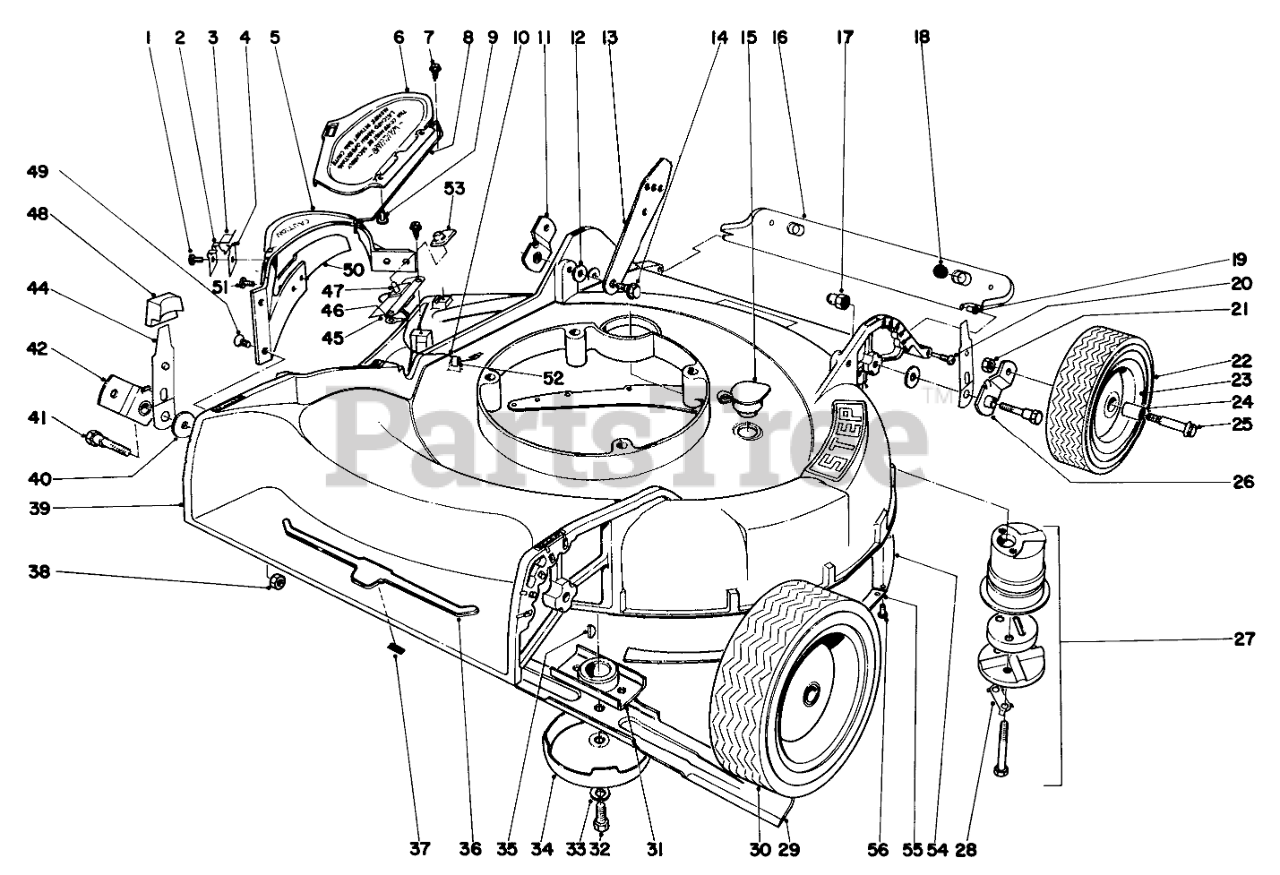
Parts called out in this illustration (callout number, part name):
2	Lower Clip
3	Upper Clip
4	Wear Plate
5	Deflector
6	Deflector (Incl. Ref. #8 & #9)
7	SCREW-HWHTF
8	Hinge Pin
9	Rivet
10	Lead Wire
11	Pivot Arm
12	SPACER
13	Handle Latch
14	SCREW-SHOULDER
15	WASHOUT PLUG
16	Safety Shield (Incl. Ref. #18 & #19)
17	Nut
18	SKID BUTTON
19	SAFTEY SHIELD BUSHING
20	SAFTEY SHIELD SCREW
21	Nut
22	8 TIRE
23	Wheel (Incl. Ref. #24)
24	Bushing
26	Pivot Arm
27	Muffler
28	CLIP - LOCKING
29	Blade
31	BLADE RETAINER WA
32	SPECIAL SCREW
33	WASHER-LOCK
34	AntiScalp Cup
35	KEY-WOODRUFF
36	Emblem, Bullshead
38	Nut
39	Housing (Incl. Ref. 54-56)
40	WASHER-PIVOT
41	5/16-18 PIVOT SCREW
42	Pivot Arm
44	Spring Arm
45	Mounting Plate
46	Ground Wire
47	Switch
48	Knob
49	Screw
50	DefIector Bar
53	Boot Switch
54	Main Skirt
55	Secondary Skirt
